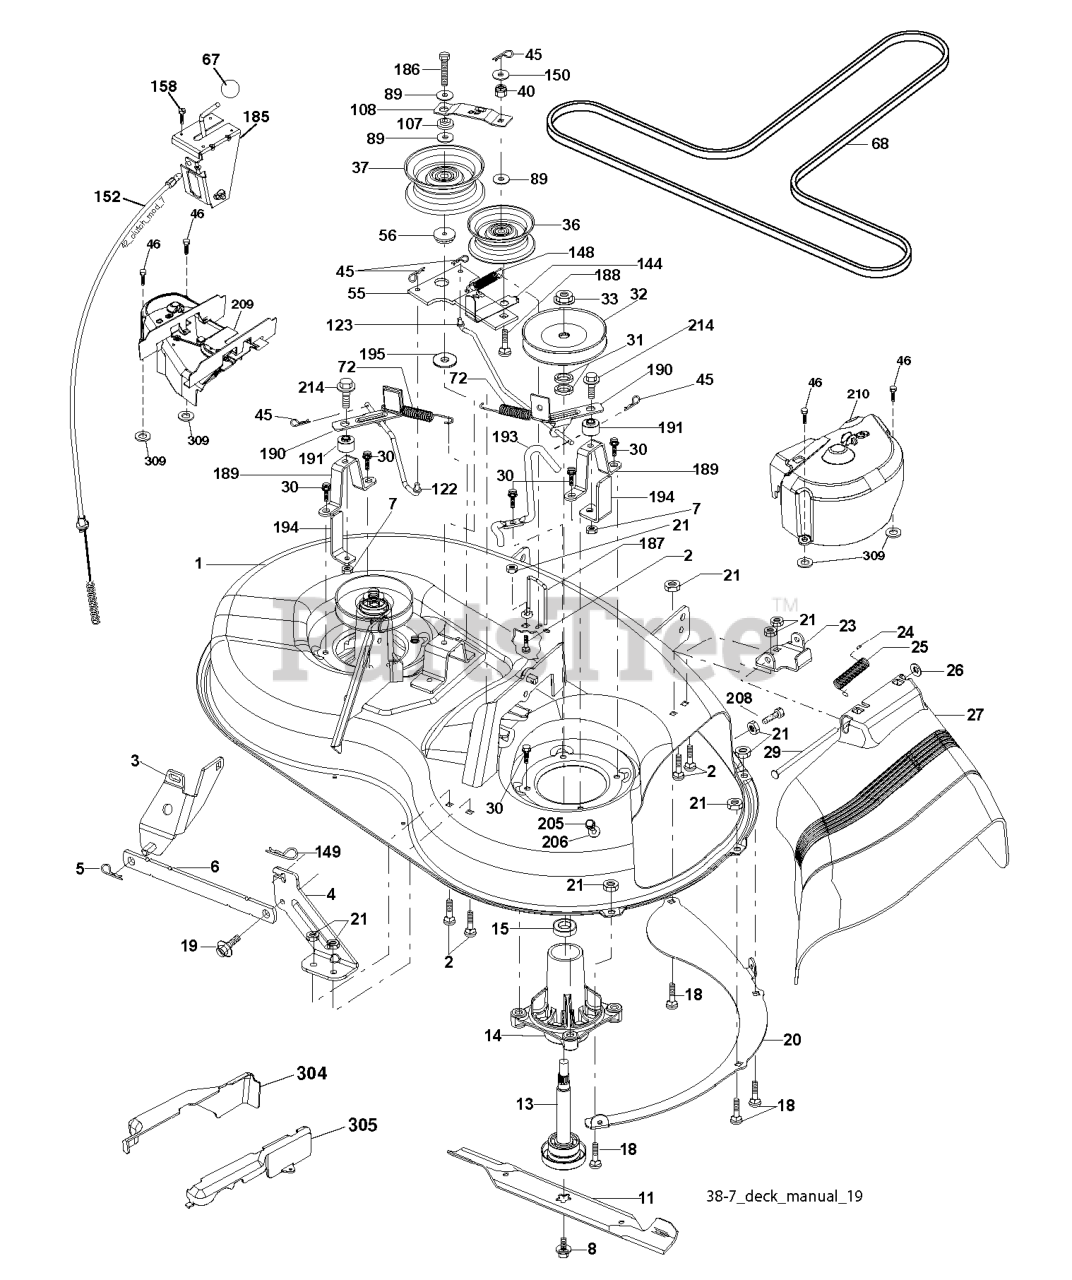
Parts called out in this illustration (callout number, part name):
1	DECK SVCX1 38/94 192556X431
2	RP BOLT 5/16-18 X3/4 ZN/YEL GR
3	BRKT ASM SWAY BAR
4	BRACKET DECK SWAY BAR 38"/42"
5	RETAINER-SPRNG RB
6	BAR SWAY DECK
7	NUT.71038.31-18.HEX.NYLOCK
8	BOLT.WASHER.ASM.7/16-2
11	BLADE 38" PREMIUM
13	SHAFT.ASM.MDRL.N/GREASE.38
14	RP.HOUSING.MANDREL.4PT.
18	BOLT
19	BOLT SHD 5/16-18
20	BAFFLE.VORTEX.FRONT.38"
21	LOCKNUT
23	BRKT.DEFLECTOR.38"2005+
24	CAP-SLEEVE LT
25	SPRING.TORSION.DEFLECT
26	NUT PUSH M
27	SHIELD ASM.DFLCTR MWR.38-7"BLK
29	ROD.HINGE
30	SCREW, WASHER HEAD
31	WASHER.SPACER.MANDREL
32	PULLEY MANDREL
33	NUT.FLANGE.LOCK.TOP
36	FLAT IDLER PULLEY
37	PULLEY.IDLER.FLAT.UNPLATED
45	RETAINER M
46	SCREW.1/4-20X5/8
56	SPACER.RETAINER.MOWER
67	KNOB T (3/8 HOLE)
68	V-BELT.MOWER.38"2005+
72	SPRING.BRAKE.RETURN.38"
89	WASHER
107	SPACER.IDLER.ARM
108	STIFFENER.IDLER.ARM
122	LINK.BRAKE.38"LEFT.2007
123	LINK.BRAKE.38"RIGHT
144	KEEPER BELT
148	IDLER RETURN SPRING
149	SPRING.RETAINER.YELLOW.ZINC
152	CABLE.CLUTCH.38".SERVICE
158	SCREW
185	HEAD ASM. CABLE CLUTCH
186	SCREW.HXWSH.3/8
187	KEEPER BELT
188	BOLT, CARRIAGE IDLER
189	STAND, BRAKE
190	ARM, BRAKE
191	BRAKE.SPACER.38".DECK
193	KEEPER BELT RH MANDREL
194	GUARD BRAKE
195	WASHER 12/32X2X10GA
205	SCREW
208	SCREW 3/8-16X1/2
214	BOLT/WASHER ASM 5/16-18
309	PALNUT 1/4
